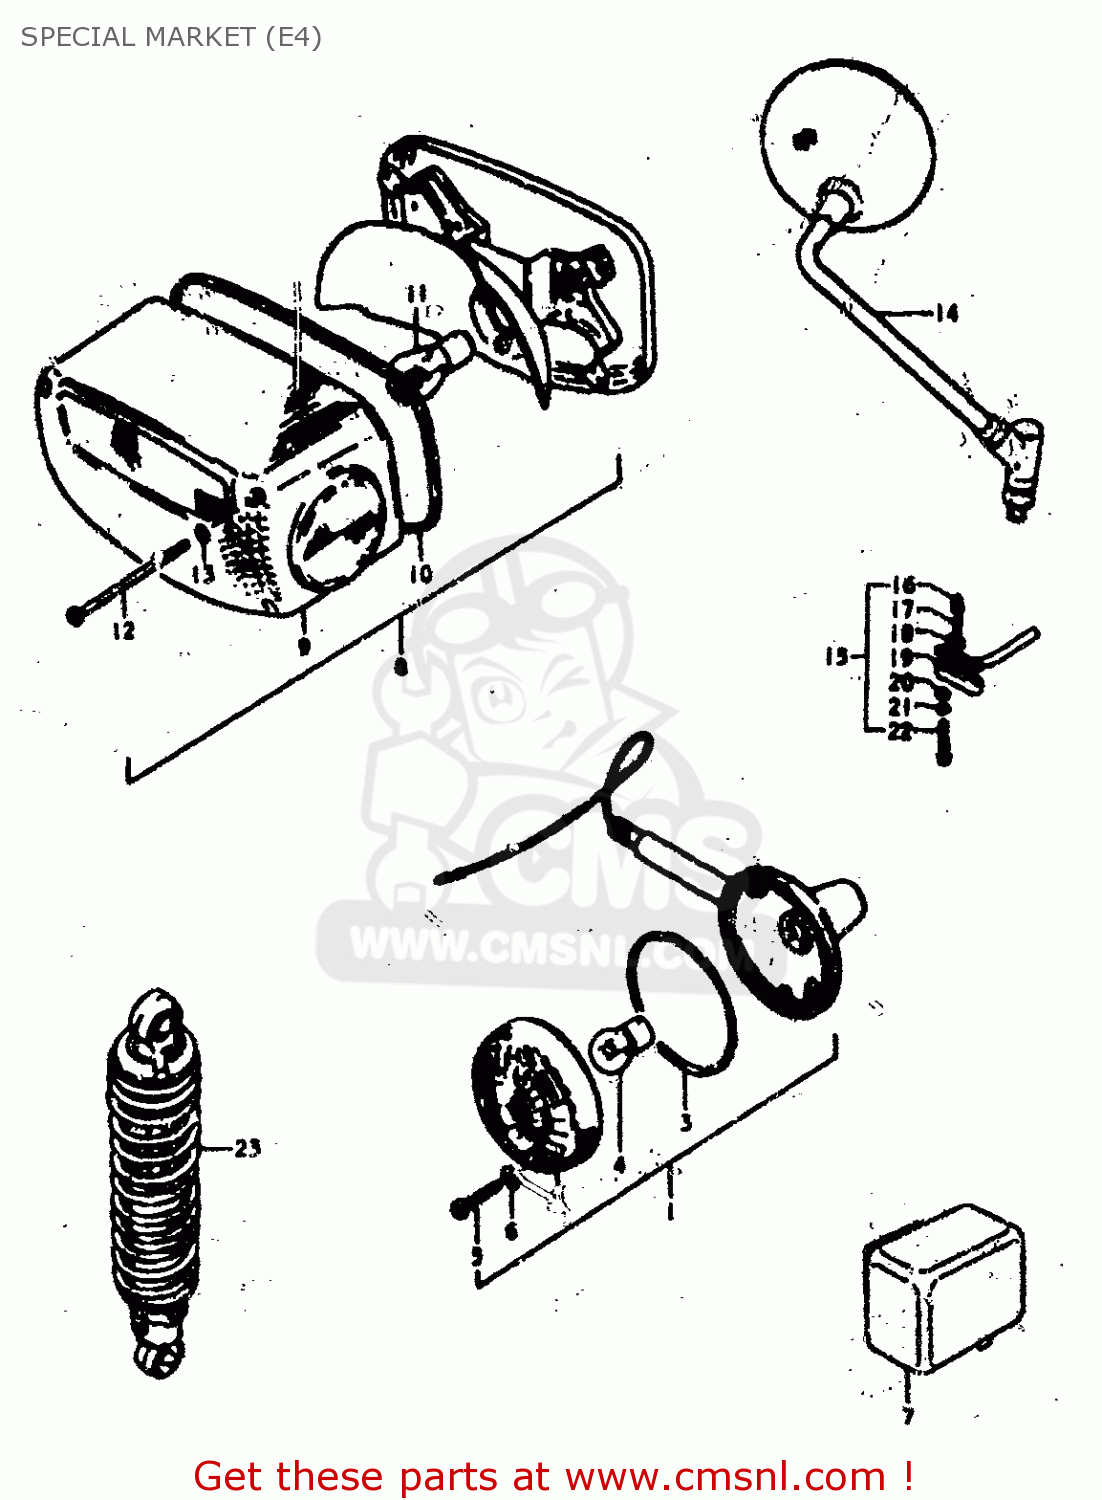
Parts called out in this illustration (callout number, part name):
1	LAMP ASSY,FRONT TURN SIGNAL
2	LENS
3	GASKET (NAS)
4	BULB 12V 21W
5	SCREW
6	GASKET (NAS)
7	RELAY,TURN SIGNAL
8	LAMP ASSY,REAR COMBINATION
9	LENS,REAR COMBINATION LAMP
10	GASKET (NAS)
11	BULB
12	SCREW (4X55)
13	GASKET (NAS)
14	MIRROR ASSY,RH
15	SWITCH ASSY,STOP
16	HOLDER
17	SPRING
18	PLATE
19	COVER,FR BK TERMINAL BASE
20	WASHER
21	LOCK WASHER
22	SCREW
23	SHOCK ABSORBER, REAR
